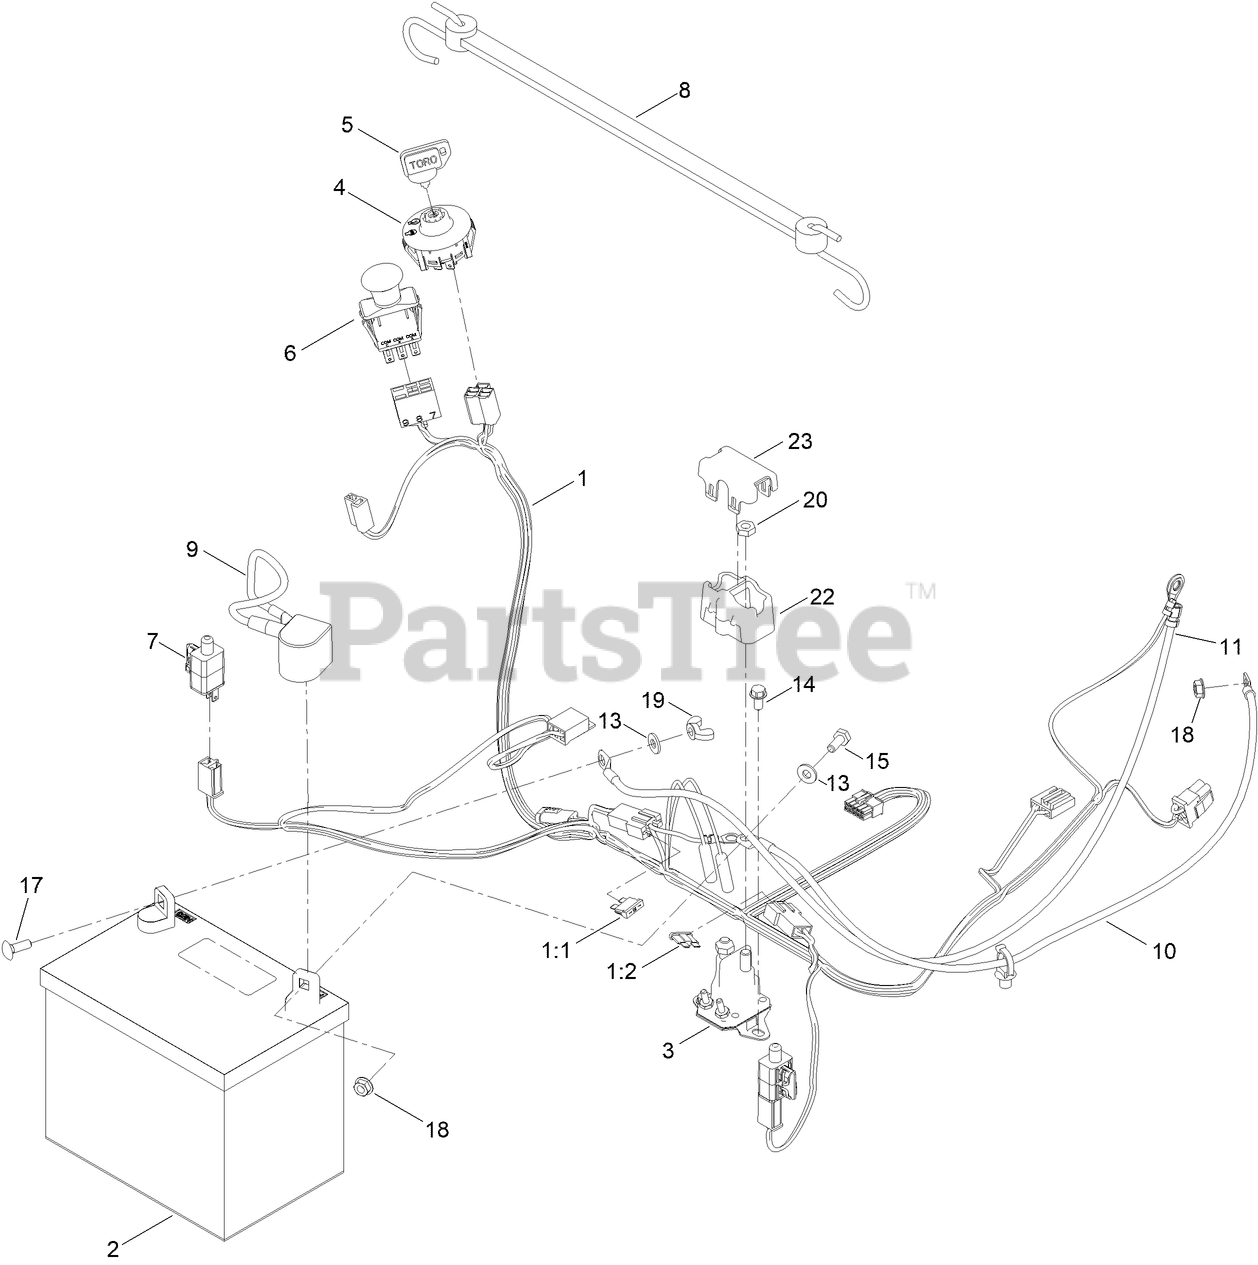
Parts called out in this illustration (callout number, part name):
1	HARNESS-WIRE
2	BATTERY
3	SOLENOID
4	SWITCH-IGNITION
5	KEY-IGNITION
6	SWITCH-PTO
7	SWITCH
8	STRAP-RUBBER
9	CABLE-BATTERY, POS
10	CABLE-BATTERY, RED (8 GAUGE)
11	CABLE-BATTERY, BLACK
13	WASHER-FLAT
14	SCREW-HWH
15	SCREW-HH
17	BOLT-CARR
18	NUT-HF
19	NUT-WING
20	NUT-JAM
22	COVER-SOLENOID
23	CAP-SOLENOID
